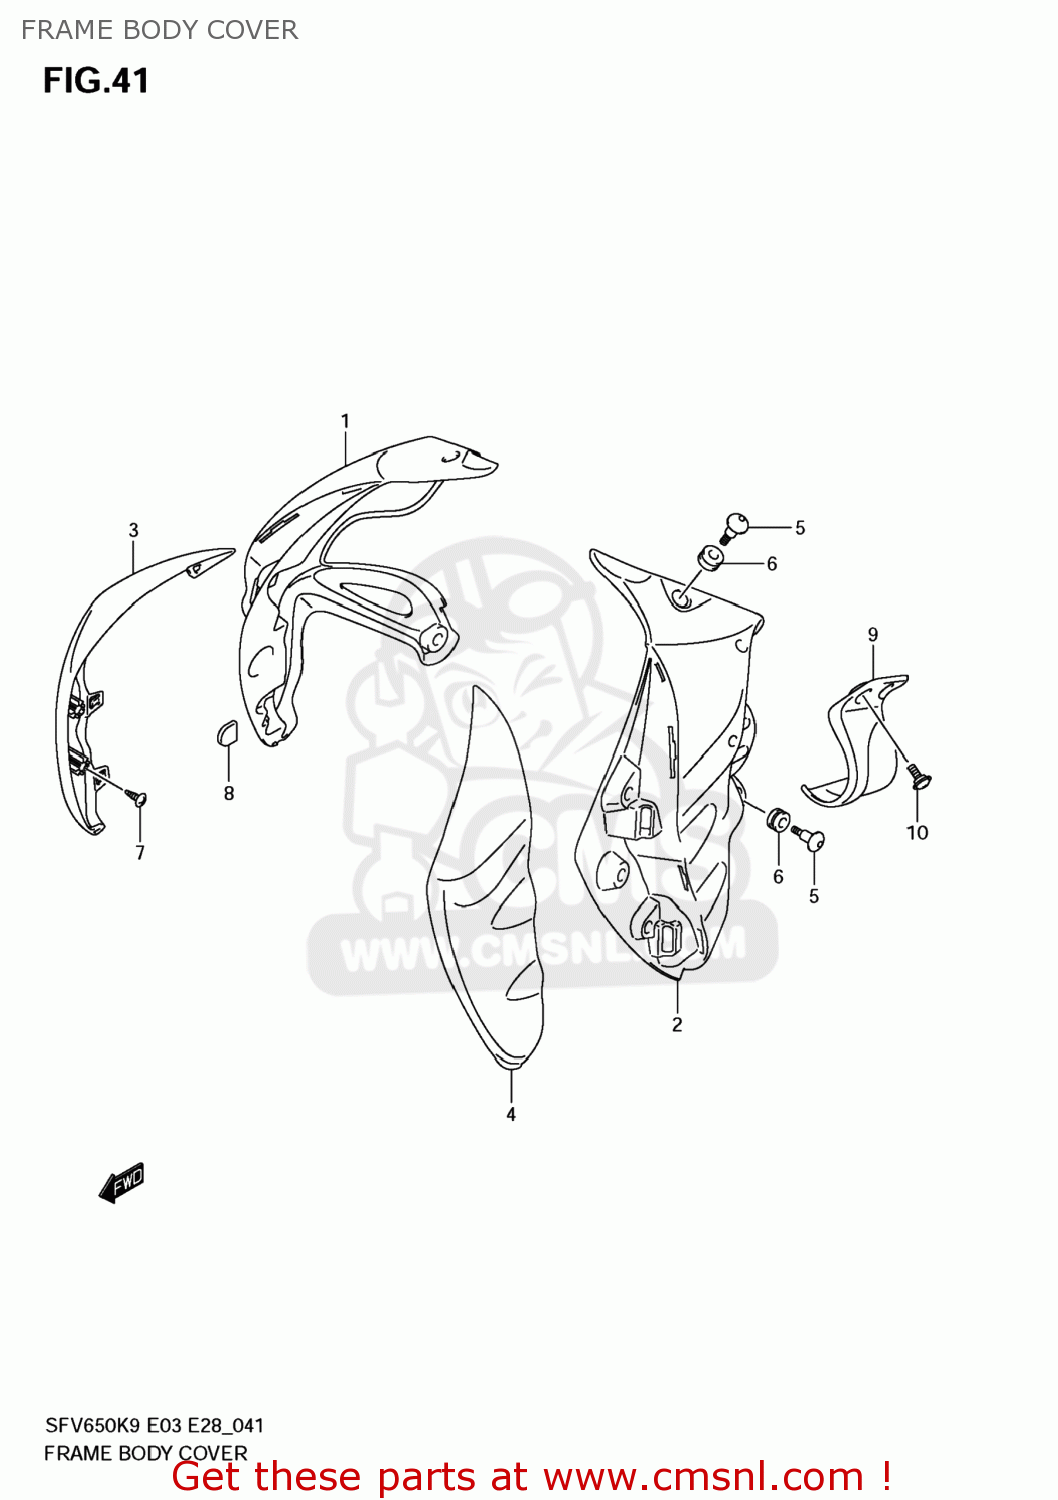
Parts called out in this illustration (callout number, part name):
1	COVER,FRAME BO
2	COVER,FRAME BO
3	COVER,FRAME BODY IN,R(WHITE)
4	COVER,FRAME BODY IN,L(WHITE)
5	SCREW(6X20)
6	CUSHION
7	SCREW
8	CUSHION
9	COVER,FRAME BODY RR,L
10	SCREW(5X13)
